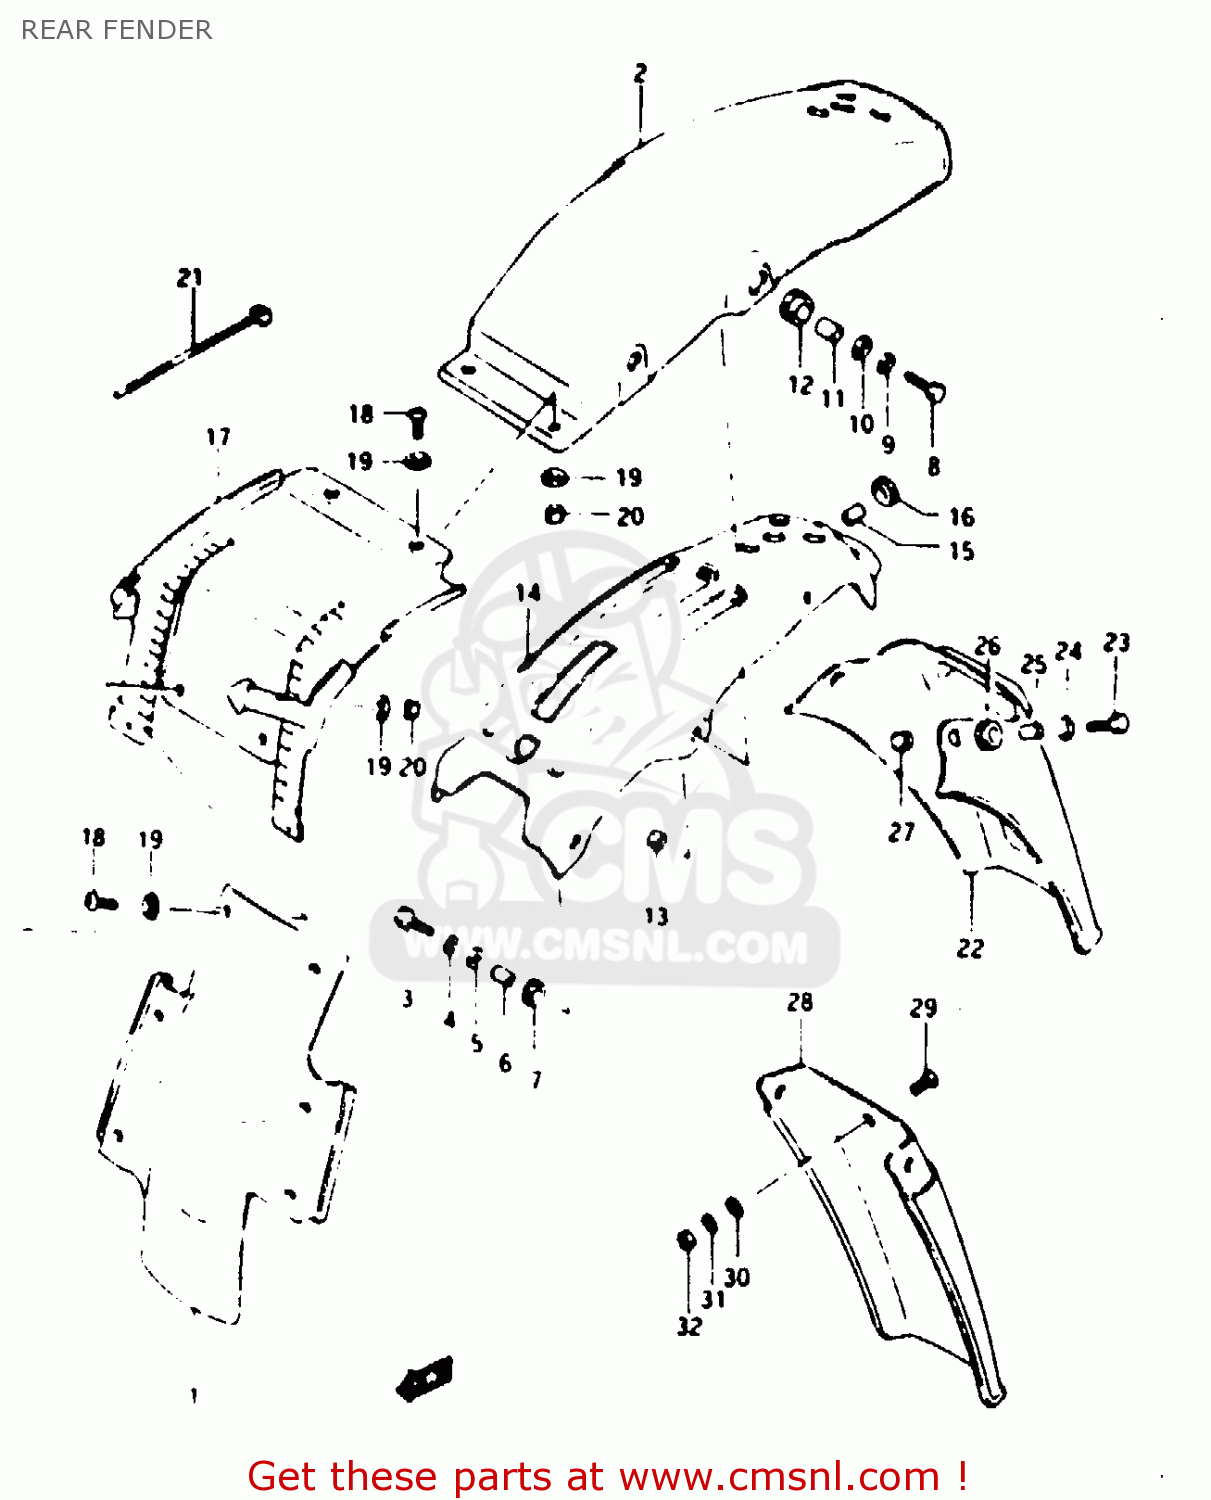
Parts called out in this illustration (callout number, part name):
1	BODY, REAR FENDER FRONT
2	FENDER, REAR (RED)
3	BOLT,M6X1X20
4	WASHER,LOCK
5	WASHER, LOWER
6	SPACER(6.1X9X7.5)
7	CUSHION
8	BOLT
9	WASHER,LOCK,8.
10	WASHER
11	SPACER (8.2X12X7.5)
12	CUSHION
13	NUT, WHEEL SET
14	REINFORCEMENT
15	SPACER (6.1X9X9)
16	CUSHION
17	MUD GUARD, FRONT
18	SCREW
19	WASHER (5.5X16X1.2)
20	NUT
21	CLAMP
22	EXTENSION,RR FENDER
23	BOLT,M6X1X20
24	WASHER
25	SPACER(6.1X9X7.5)
26	CUSHION
27	NUT
